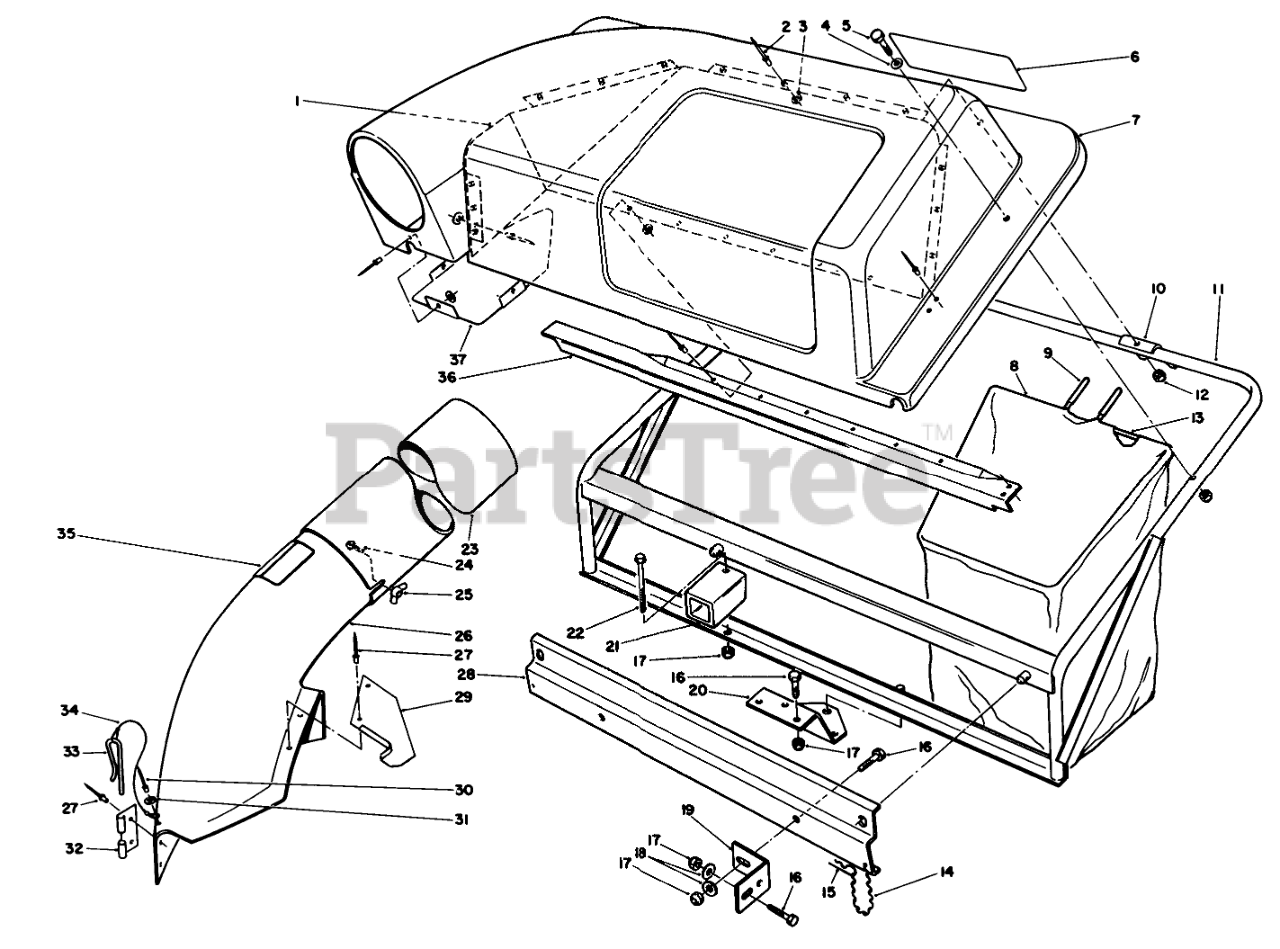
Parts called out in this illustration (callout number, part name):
1	Screen Cover
2	RIVET-POP
3	WASHER-FLAT
4	WASHER-PLAIN
5	SCREW-HH
6	TWIN BAGGER DECAL
7	Cover
9	GRIP-HANDLE, BAG
10	BAG FRAME BRKT
11	Frame
12	NUT-LOCK, CAP
13	Frame-Bag
14	6-LINK CHAIN W/HOOK
15	PIN-HAIR
16	SCREW-HH
17	NUT-LOCK, NI
18	WASHER-PLAIN
19	MTG BRACKET
20	MTG PLATE B
21	FRAME SUPT TUBE B
22	SCREW-HH
23	TUBE(ROUND&LONG)
24	BOLT-CARR
25	NUT-WING SPECL
26	Chute Assembly (Incl. Ref. #27, 29-35)
27	RIVET-BLIND
28	Bracket Frame Support
29	CHUTE SUPT BRKT
30	RIVET-BLIND
31	WASHER-PLAIN
32	BRACKET-MOUNTING, CHUTE
33	PIN-LOCKING, CHUTE
34	LANYARD
35	DECAL-DANGER
36	SCREEN SUPT BRKT B
37	Shield Cover
